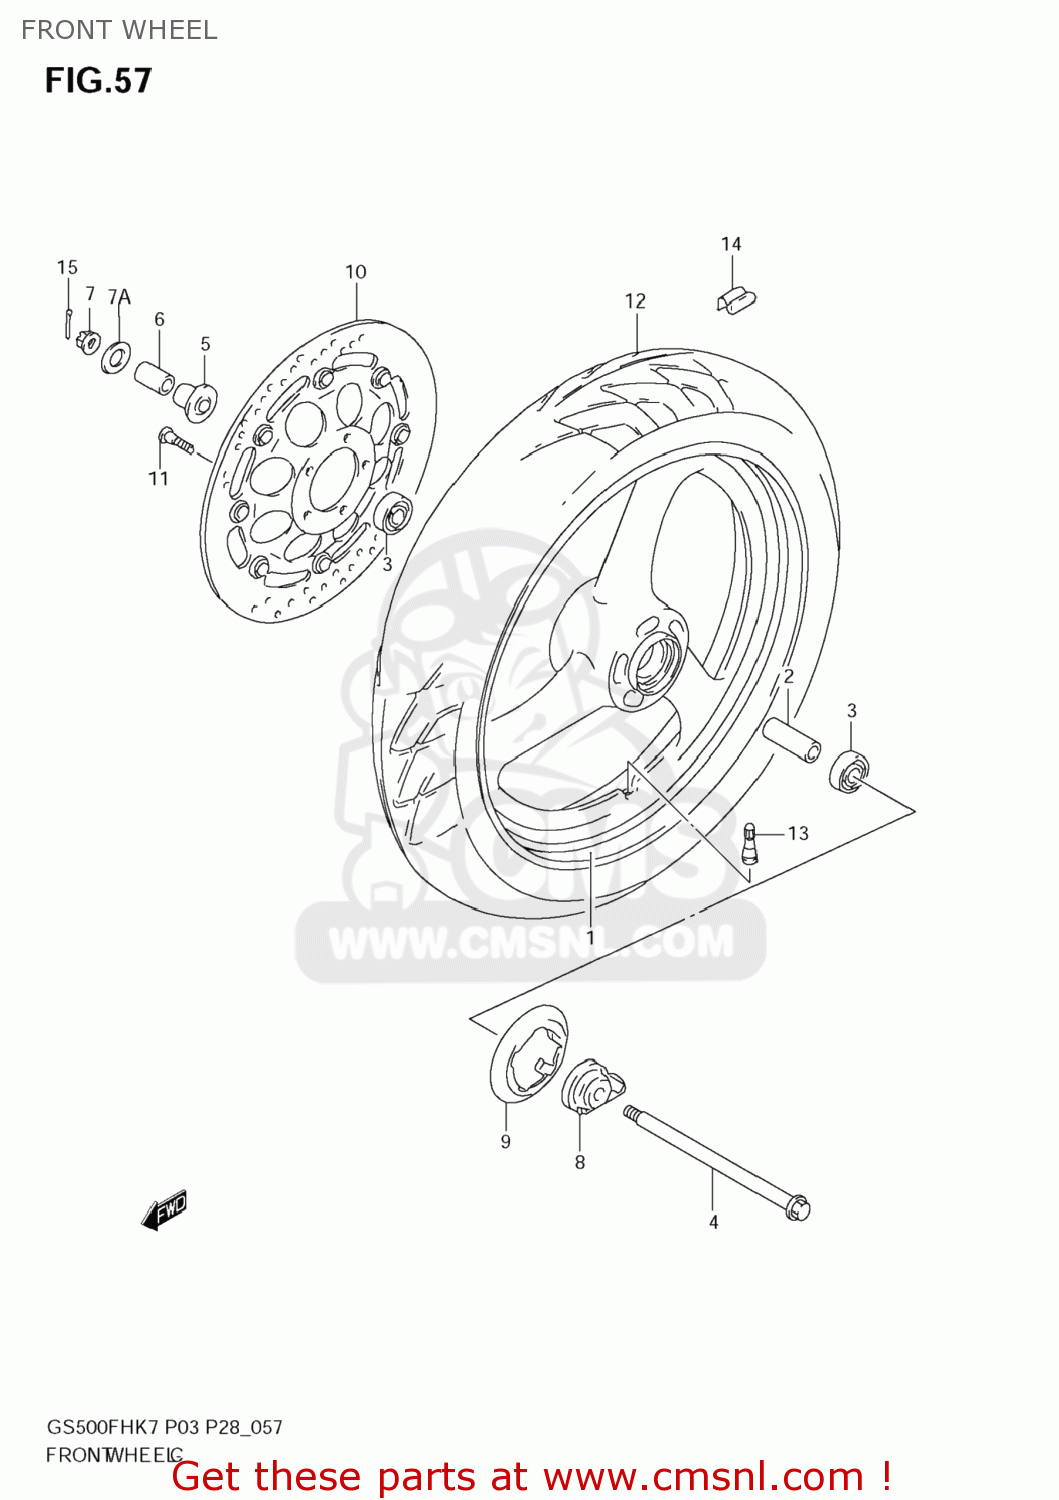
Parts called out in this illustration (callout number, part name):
1	WHEEL,FR(MT3.00X17)
2	SPACER(15.3X21.7X63)
3	BEARING
4	AXLE,FR
5	SPACER, FRONT AXLE RH
6	SPACER, FRONT AXLE RH
7	NUT
7A	WASHER(12.5X32X4.5)
8	BOX ASSY,SPEEDOMETER GEAR
10	DISC, FRONT LH
11	BOLT 8X33
12	TIRE, FRONT,110/70-17 54H
13	VALVE
14	BALANCER,WHEEL(10G)
15	PIN
